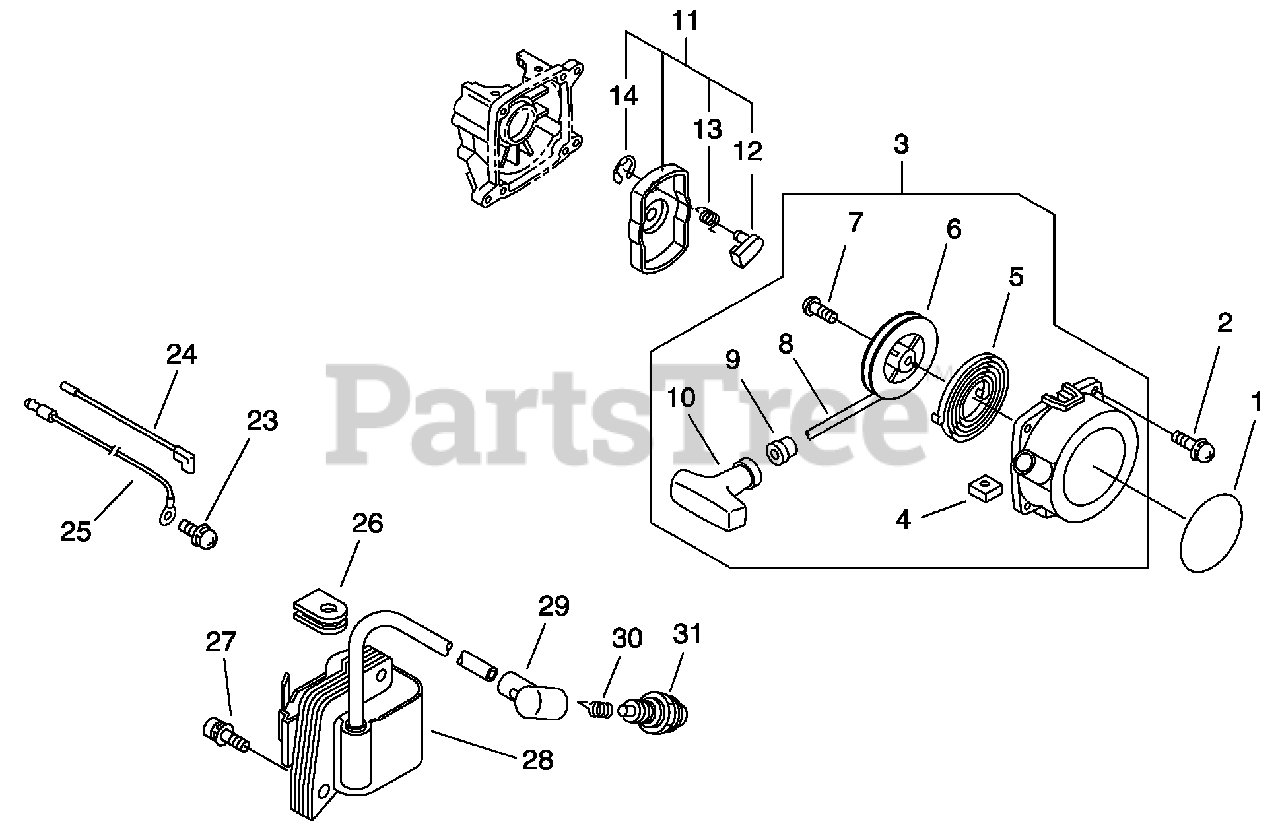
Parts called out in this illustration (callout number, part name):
1	LABEL - ECHO
2	SCREW - 4X14
3	STARTER ASSY
4	NUT - 5 -- SQUARE
5	SPRING, REWIND
6	REEL, ROPE
8	ROPE, STARTER
9	GUIDE, ROPE
10	GRIP, STARTER
11	STARTER PAWL ASSY
12	PAWL, STARTER
13	SPRING, RETURN
14	RING, RETAINING - 4
23	SCREW - 5X10
24	LEAD - IGNITION
25	LEAD - GROUND
27	SCREW - 5X22
28	COIL, IGNITION
29	CAP, SPARK PLUG
30	TERMINAL, SPARK PLUG CAP
31	SPARK PLUG -- BPM-7A
